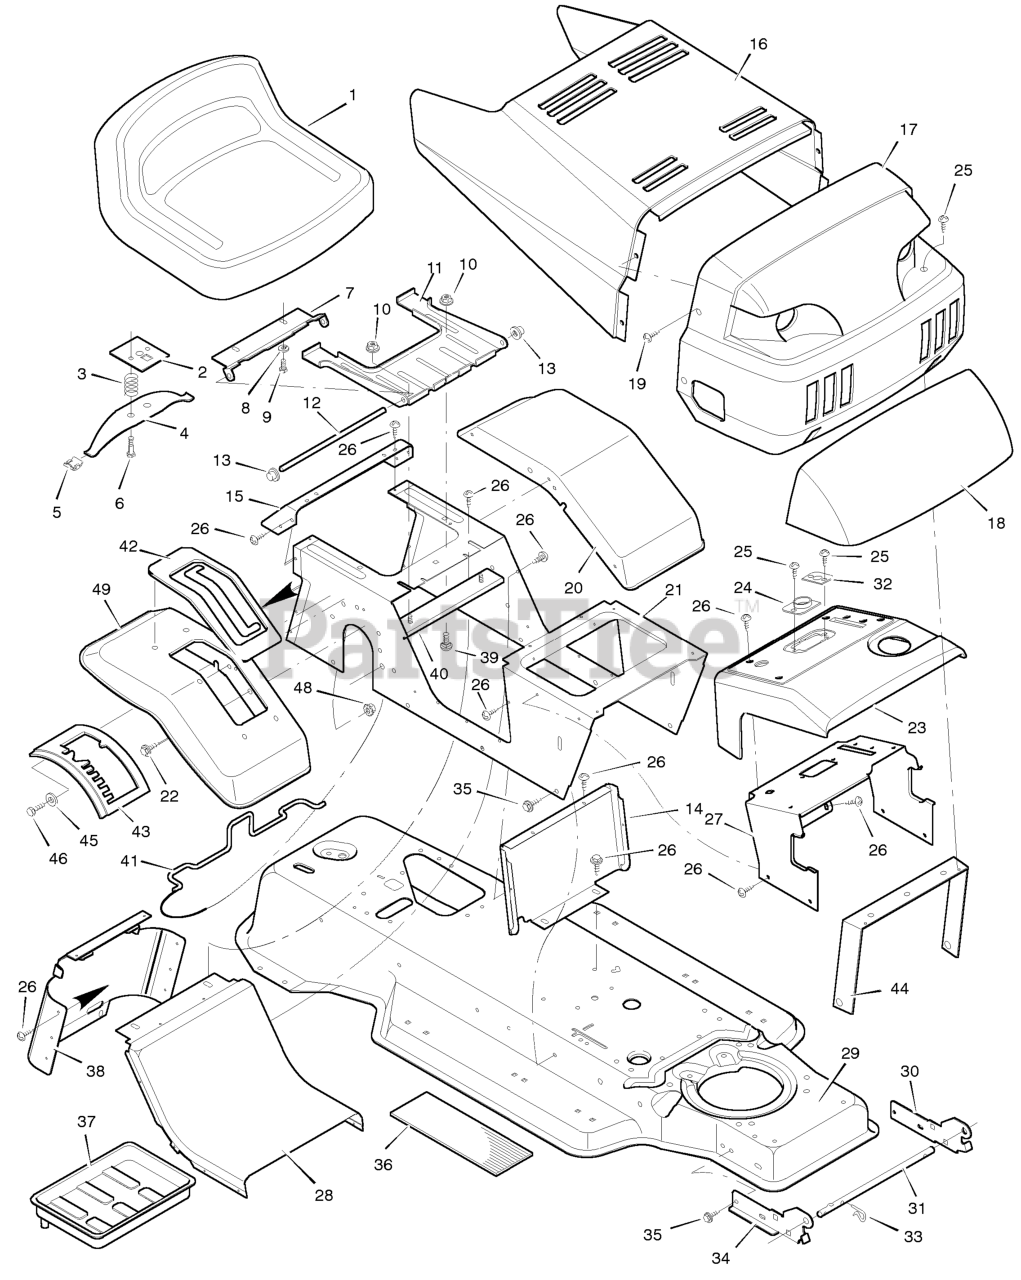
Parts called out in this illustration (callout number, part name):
2	Plate Assembly, Switch
3	Spring, Compression
4	Spring, Seat
5	Glide, Spring
6	Bolt, Shoulder
7	Support, Seat
8	Lockwasher
9	Bolt, Hex
10	Locknut, Flange
11	Bracket, Pivot
12	Rod, Pivot
13	Cap, Push On
14	Insert, Front
15	Fender, Apron
17	Grille Assembly
21	Console Assembly
23	Dash Panel
24	Bearing, Steering
26	Screw
27	Support, Dash
28	Insert, Rear
29	Frame Assembly
30	Bracket, Left Grille
31	Rod, Pivot
32	Bearing
33	Pin, Hair
34	Bracket, Right Grille
37	Tray, Battery
38	Cap, Console
39	Bolt
40	Channel Assembly
41	Clamp, Battery
42	Cover, Shift
43	Gate, Shift
44	Brace, Grille
46	Bolt, Hex
48	Locknut
49	Fender, SOG
